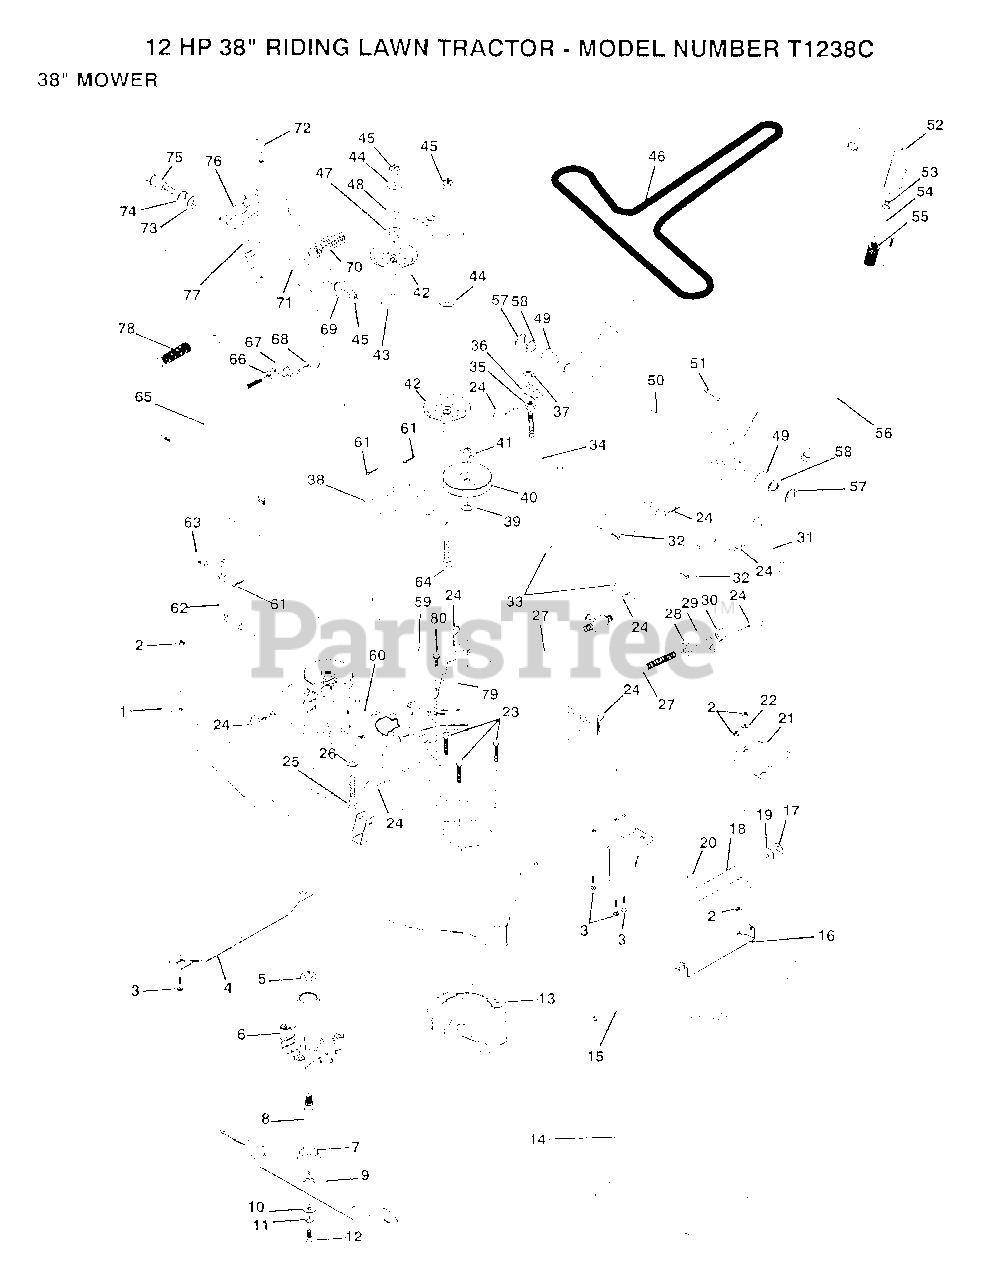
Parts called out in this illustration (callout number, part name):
3	BOLT
4	RUNNER-LH M
5	BEARING
6	HSG ASM MANDREL
7	BEARING.BALL
10	WASHER BLADE
12	BLADE BOLT
14	DEFLECTOR-SHLD T
15	ROD-HINGE T
17	NUT PUSH M
19	WASHER
20	CAP-SLEEVE LT
21	RUNNER RH
22	WASHER M
25	BOLT
26	WASHER GT
27	LINK.FRONT
28	NUT
29	TRUNION
30	NUT.LK.W/WSH.1/2.
31	LINK LIFT RH
32	SPRING PIN
33	SUSP ARM REAR
34	LIFT LINK LH
35	NUT
38	IDLER ARM ASSY
39	WASHER
42	FLAT IDLER PULLEY
43	SPACER RETAINER
44	WASHER GT
46	BELT-V.88.12.MW
47	RETAINER SPACER
48	IDLER ARM STIFF
49	NYLON BEARING
51	PIN-GROOVE LT
52	GRIP
58	WASHER
59	BRAKE ROD RH
60	BRAKE ROD LH
62	PIVOT ROD
63	CLUTCH ROD SECOND
64	BOLT
66	NUT
67	TRUNION
68	RETAINER M
69	BUSHING
71	CLUTCH ARM PRI AS
73	WASHER
74	RING
75	SHOULDER BOLT
76	SPRING KEEPER
77	CLUTCH ARM SECOND
78	RETURN SPRING
79	BRAKE ASM
80	SCREW
